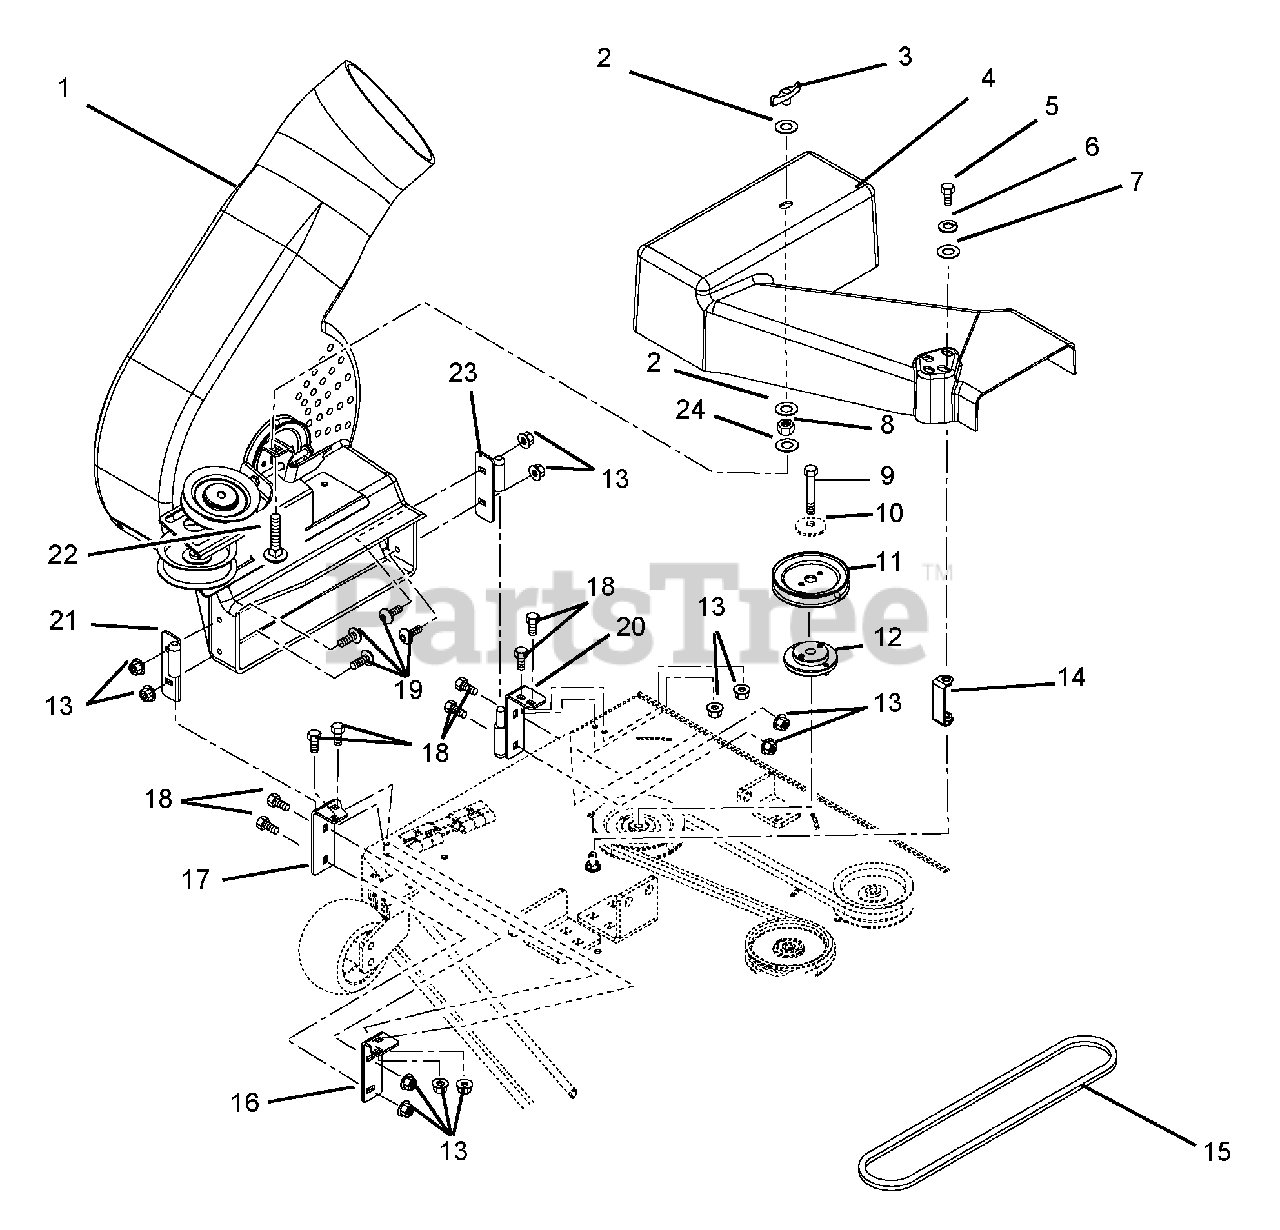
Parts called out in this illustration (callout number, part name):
1	Housing, Blower
2	Washer-Flat-Steel.38 x 1.50 x .062
3	Knob- Wing .312-18
4	Belt Cover
5	Bolt-Hex .38-16 x .75 - Grade 5
6	Washer-Locking .38 x .094 Regular
7	Washer-Flat-Steel .438 x 1.00 x .083
8	Nut-Jam .312-18
9	Bolt-Hex .38-16 x 1.75 - Grade 8
10	Washer, Flat Steel .406 x 1.50 x .245
11	Sheave, 3.00 Diameter
11	Sheave, 4.00 Diameter
12	Assembly, Sheave Adapter
13	Nut-Locking-Top-Flange .25-20
14	Spacer, Cover
15	V-Belt
16	Bracket, Front
17	Weldment, Front Mount Bracket
18	Bolt-Hex .25-20 x .75 - Grade 5
19	Screw-Machine .25-20 x .75
20	Weldment, Rear Mount Bracket
21	Weldment, Housing Mount Right Hand
22	Bolt-Round Head Square Neck .31-18 x 1.50
23	Weldment, Housing Mount Left Hand
24	Washer-Flat-Steel .312 x .734 x .065
